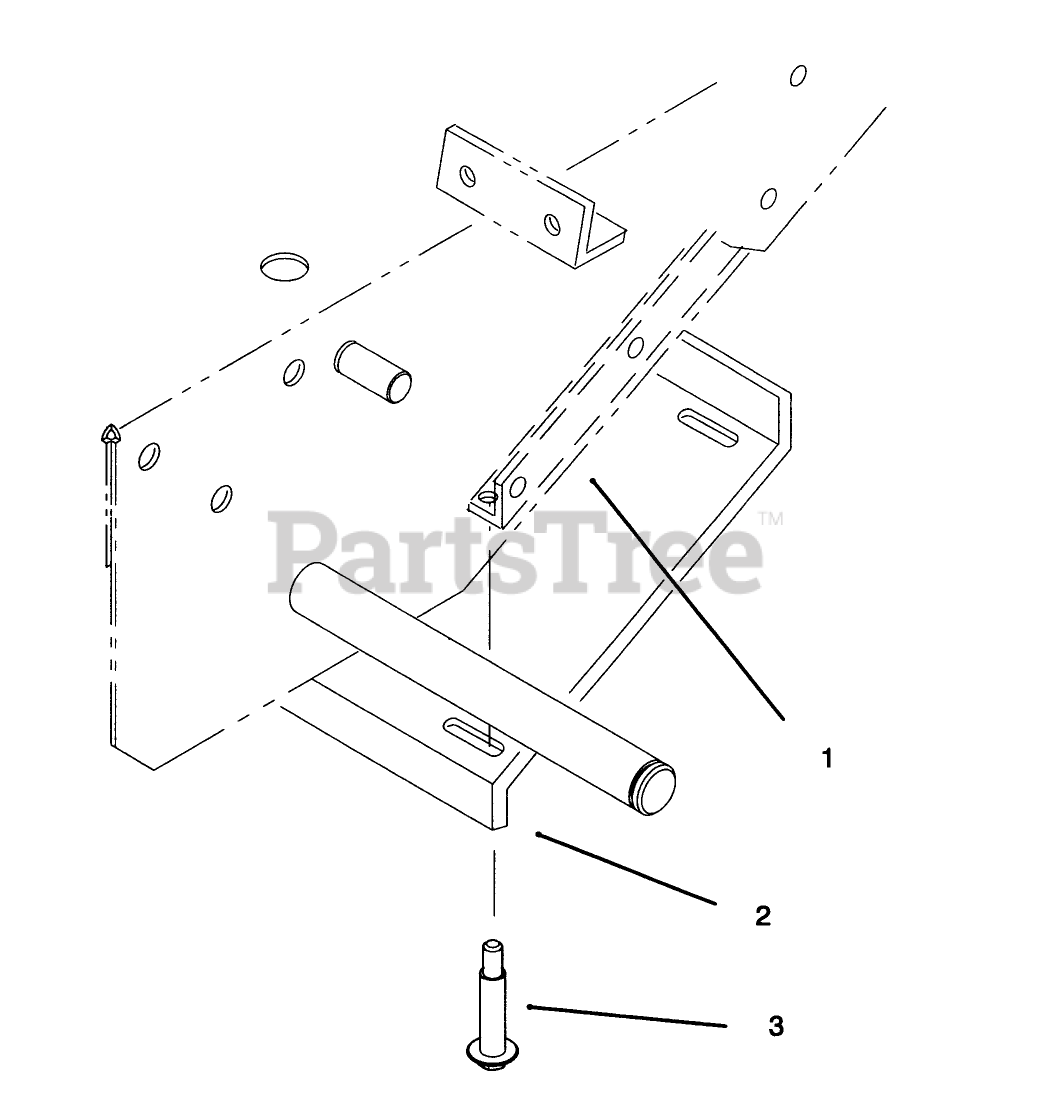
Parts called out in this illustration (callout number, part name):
1	Mount-Angle
2	Panel-Bottom
3	SCREW
